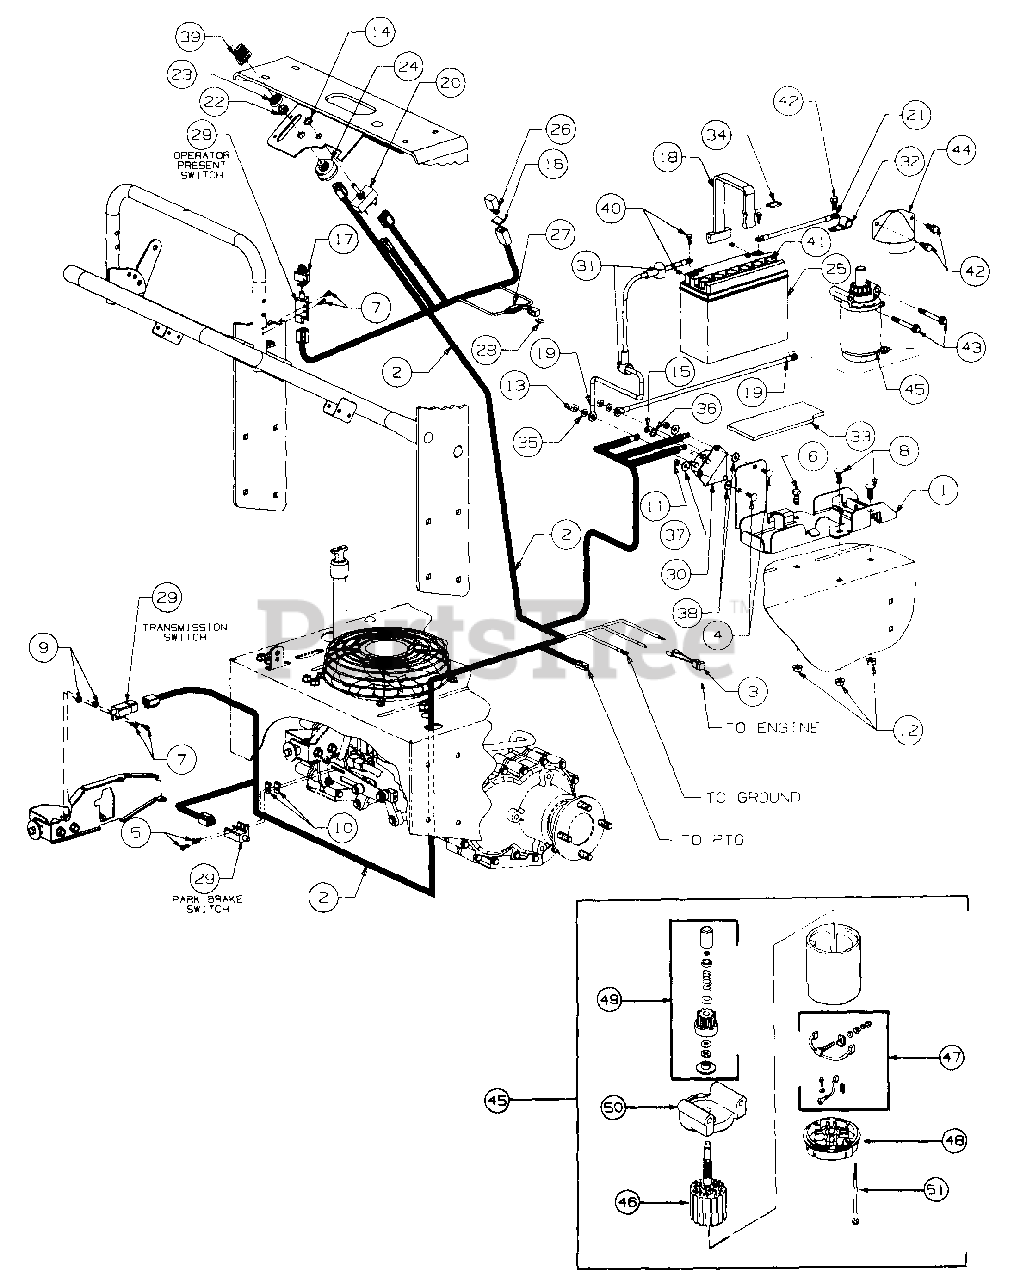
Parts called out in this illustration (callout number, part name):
1	Bracket, Battery
2	Harness, Electric Start
3	Harness, Kohler Adapter
4	Bolt, Carriage, 1/4-20 X .62 lg
5	Screw, Truss Machine, #10-24 X .50 Lg
6	Screw, Hex Cap, 3/8-16 X .88 Lg GR5
7	Screw, Pan Hd Cutting, #10-24 X .75 Lg
8	Bolt, Carriage, 3/8-16 X 1.0 Lg GR5
9	Nut, Hex Lock, #10-24
10	Nut, Speed
11	Nut, Hex Center Lock, 1/4-20
12	Nut, Hex Flanged, 3/8-16
13	Nut, Hex, 5/16-18 GR5
14	Nut, Hex, 1/2-27 X .100 Thk
15	Nut, Hex Sems, #10-32
16	Gasket, Silicone
17	Cover, Protective
18	Strap, Battery Retainer
19	Wire, Insulated, 6 Ga. Red
20	Switch, PTO
21	Wire, Insulated, 6 Ga. Black
22	Nut, Ignition Switch
23	Cap, Ignition Switch
24	Switch, Ignition
26	Relay
27	Holder, Inline Fuse
28	Fuse, 20 Amp Mini
29	Switch, Double Poled Plunger
30	Solenoid
31	Cover, Terminal, Red
32	Clip, Cable
33	Tray, Protective Battery
34	Hook, Wire Rectangular
35	Washer, Lock, 5/16
36	Washer, External Lock, 3/8
37	Washer, Bell, .265 X .75 X .062 Thk
38	Washer, Int-Ext Lock, 1/4
39	Key, Ignition (Set of 2)
40	Bolt, Battery (Set of 2)
41	Cap, Battery
42	Screw, Mounting, M5 X 0.8 X 10
43	Screw, Mounting, M8 X 1.25 X 22
44	Shield, Starter Drive
45	Starter Assy
47	Kit, Brush & Spring
48	Cap, Commutator End
50	Cap, Drive End
